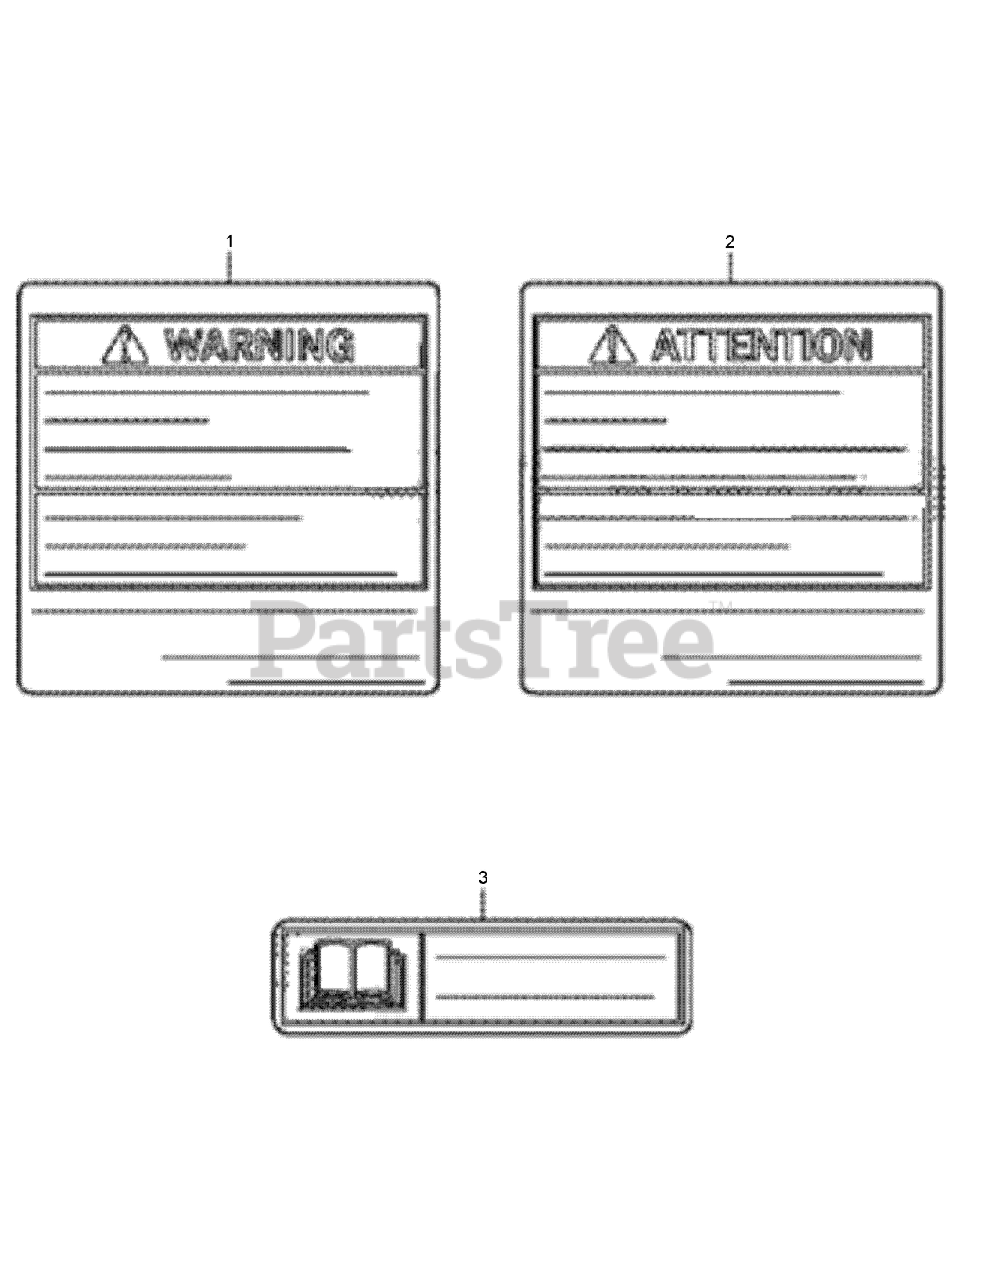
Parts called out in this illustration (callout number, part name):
1	MARK-OPERATOR CAUTION (ENGLISH)
2	MARK-OPERATOR CAUTION (FRENCH)
3	LABEL-CAUTION
